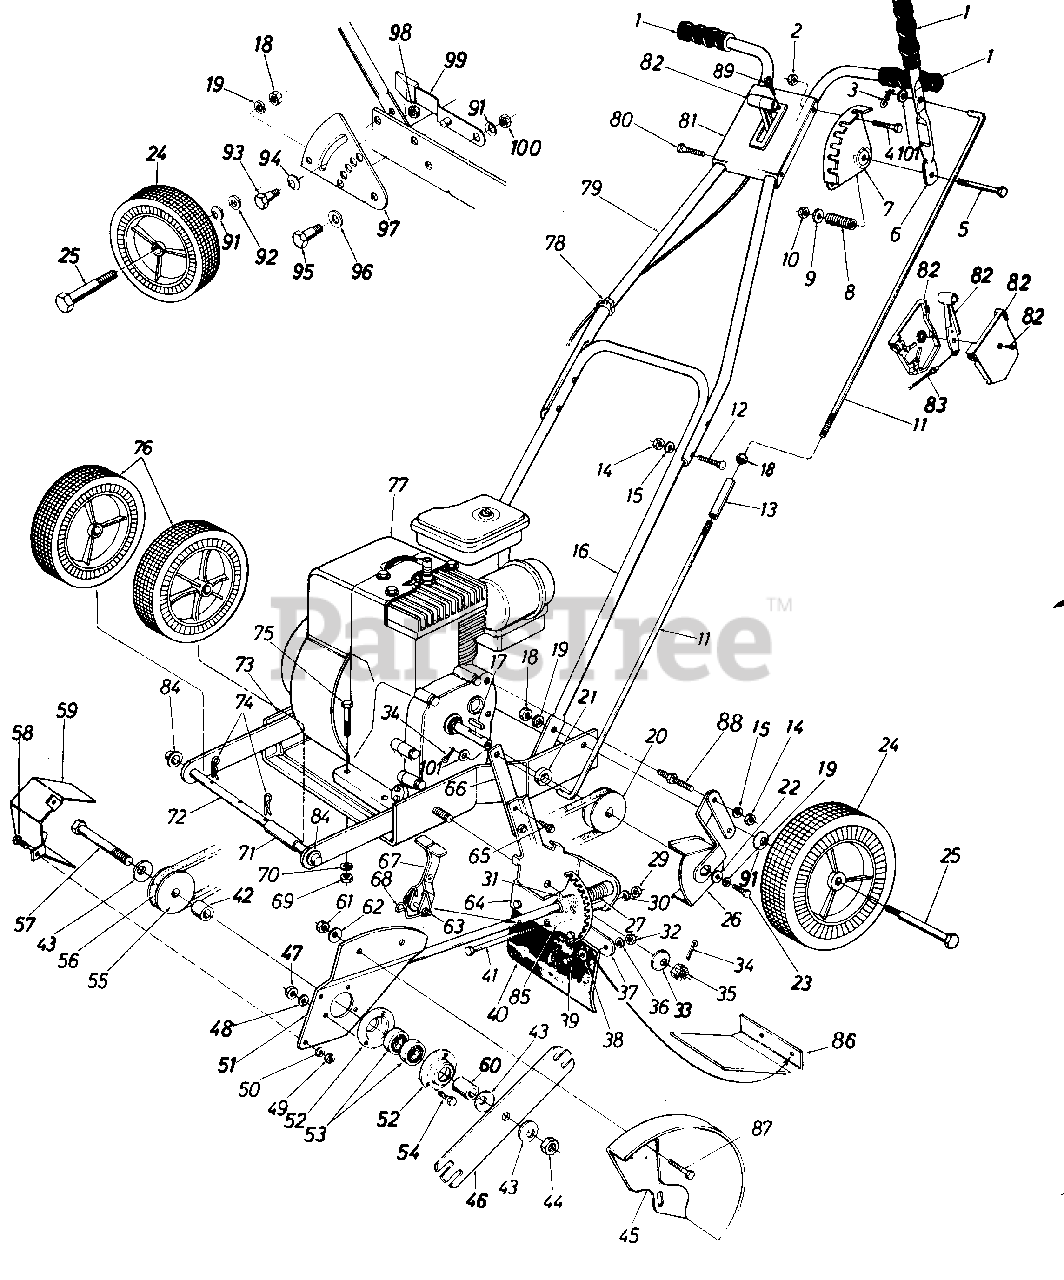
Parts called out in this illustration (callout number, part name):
1	Black Grip
2	Hex L-Nut 1/4-20 Thd.
3	Cotter Pin 1/8" Dia.
4	Hex Bolt 1/4-20 x 1.25" Lg.
5	Hex Bolt 5/16-18 x 1.75" Lg.
8	Compression Spring 1.38" Lg.
9	Fl-Wash..344" I.D.
10	Hex L-Nut 5/16-18 Thd.
11	Clutch Rod Half 18.25 Lg.
12	Carriage Bolt 1/4-20 X 1.25 Lg.
13	Rod Adjustment Link
14	Hex Nut 1/4-20 Thd.
15	L-Wash. 1/4" I.D.
16	Lower Handle (Painted)
17	Sq. Key 3/16" X .75" Lg.
18	Hex Nut 3/8-16 Thd.
19	L-Wash. 3/8 I.D.
20	Engine Pulley
21	Spacer.75" I.D.
22	Fl-Wash. .385 I.D.
23	Hex Bolt 3/8-24 X l" Lg.
24	Rear Wheel Ass'y. 8 X 1.75"
25	Shoulder Bolt .498" Dia.
26	Belt Guard Ass'y.
27	Compression Spring
29	Hex Nut 5/16-18 Thd.
30	L-Wash. 5/16" I.D.
31	Spring Pin Spir. 3/16" Dia.
32	Hex Nut 1/4-20 Thd.
33	Bell-Wash. .535" I.D.
34	Cotter Pin 1/8" Dia.
35	Hex Slotted Nut 1/2-20 Thd.
36	L-Wash. 1/4" I.D.
39	Hex Bolt 1/4-20 x .50" Lg.
41	Hex Bolt 5/16-18 x 4.5" Lg.
42	Spacer 1.030" Lg.
43	Bell-Washer..63" I.D.
44	Hex Ins. L-Nut 5/8-18 Thd.
47	Hex Nut 1/4-20 Thd.
48	L-Wash. 1/4" I.D.
49	Hex Nut 1/4-20 Thd.
50	L-Wash. 1/4" I.D.
53	Ball Bearing .62" I.D.
54	Hex Bolt 1/4-20 x .62" Lg.
55	3/8""V"-Pulley
56	"V"-Belt
57	Hex Bolt 5/8-18 x 4.5" Lg.
58	Hex Bolt 1/4-20 x .625" Lg t
60	Sleeve.90" Lg.
61	Hex Nut 5/16-18 Thd.
62	Bell-Wash. .345" I.D.
63	Spring Pin Spir. 1/4" Dia.
68	Torsion Spring
69	Hex Nut 5/16-18 Thd.
70	L-Wash. 5/16" I.D.
71	Spacer 1.62" Lg.
72	Axle 8.75" Lg.
73	Base Ass'y.
74	Hairpin Cotter 1/2" Dia.
75	Hex Bolt 5/16-18 x 1.5" Lg.
76	Front Wheel Ass'y. 7" x 1.50"
77	Engine
78	Cable Tie
79	Upper Handle (Painted)
80	Hex Bolt 1/4-20 x 1" Lg.
83	Throttle Control Wire 30" Lg.
84	Push Cap 1/2" Dia.
85	Spacer 3.765" Lg.
88	Stud 1/4-20 x 2.12" Lg.
89	Self-Tap Scr. #10 x .50" Lg.
91	Bell-Wash. .40" I.D.
92	Fl-Wash. .39" I.D.
93	Shld. Bolt .5" Dia.
94	Bell-Wash. .515" I.D.
95	Shld. Bolt .50" Dia.
96	Fl-Wash. .51" I.D. x 1"
99	Spring Adj. Lever
100	Hex Jam Nut 3/8-16 Thd.
101	Fl-Wash. 3/8" I.D.
